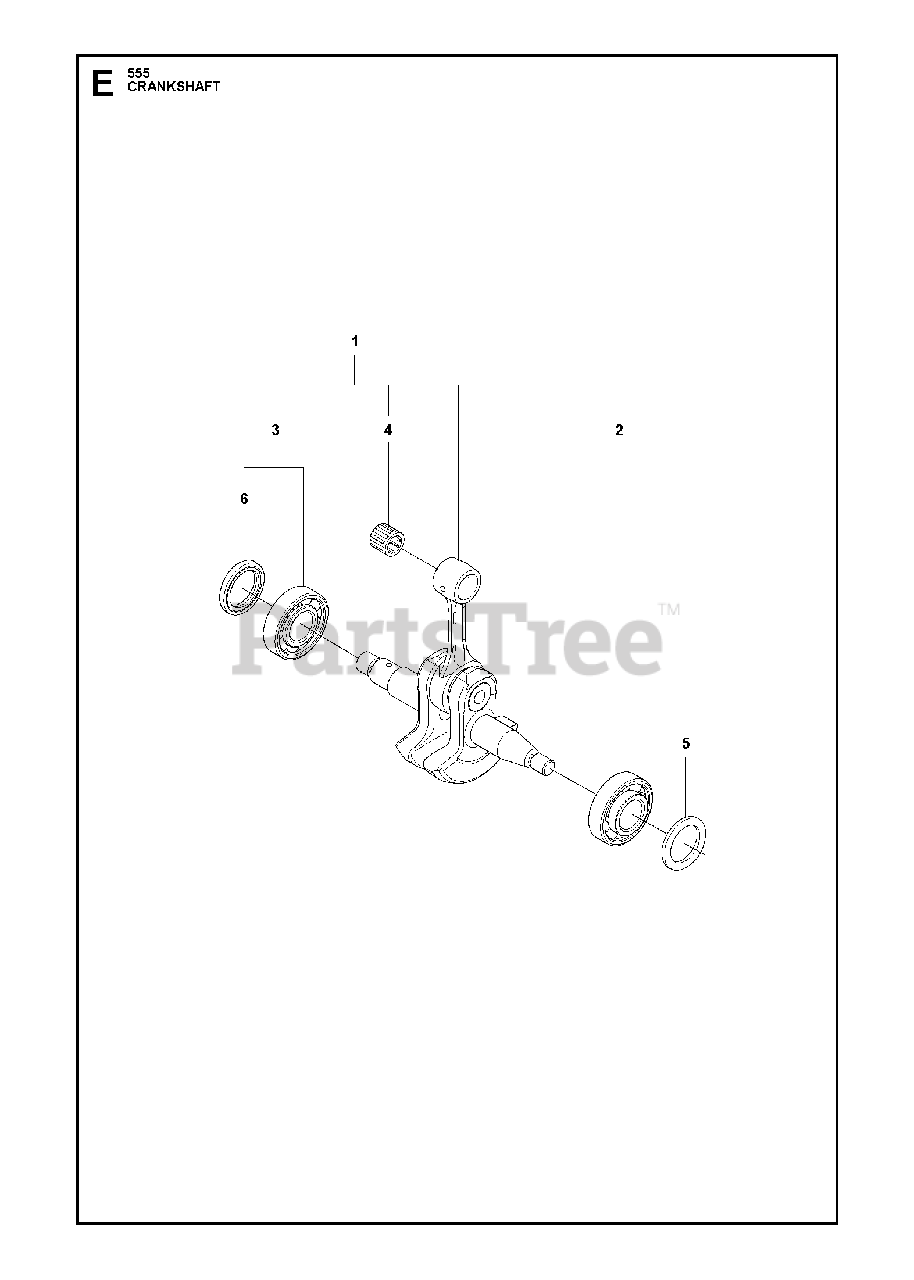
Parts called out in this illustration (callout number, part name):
1	CRANKSHAFT ASSY
2	BALL BEARING
3	BALL BEARING
4	NEEDLE BEARING
5	RADIAL SEAL
6	RADIAL SEAL
